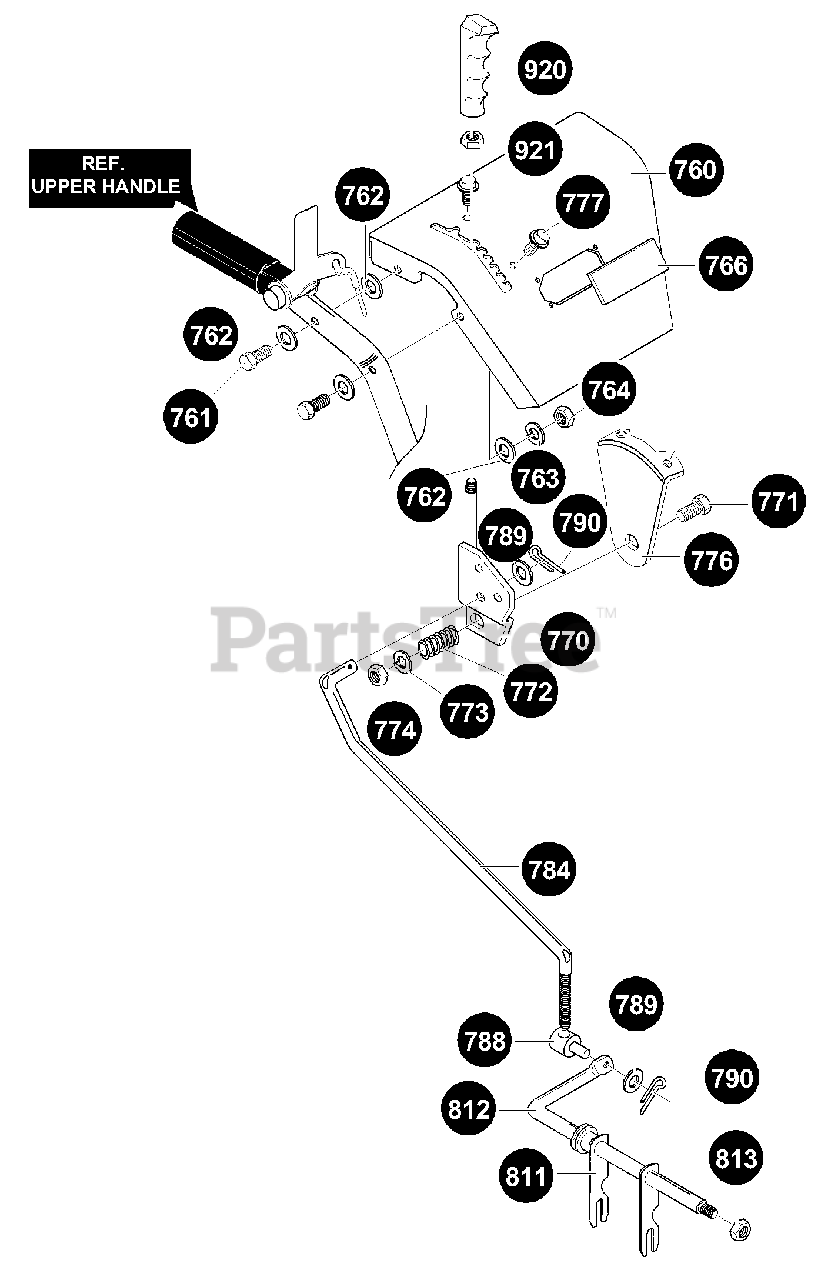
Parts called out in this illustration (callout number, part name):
760	PANEL, CONTROL W/LIGHT
761	SCREW, 5/16-18X1.75
762	FLATWASHER .344X.69X.065
763	WASHER HVSPTLK .328X.60X.09
764	NUT, 5/16-18 REGHEX
766	PLATE, PANEL
770	HANDLE ASSY SPEED CONTROL
771	SCREW 3/8-16X2.00
773	FLATWASHER .406X.81X.065
774	NUT, 3/8-16 HEXNYL
776	BRACKET, SPEED CONTROL
777	SCREW, 5/16-18X.75 WAHHTAP
780	PIN, COTTER .090DIAX.75LG
781	FLATWASHER, .344X.69X.065
784	ROD, SPEED CONTROL
788	NUT, TRUNNION 5/16-24
789	FLATWASHER .344X.69X.065
790	COTTER PIN .090DIAX.73LG
811	BEARING, FLANGED
812	ROD, ASSY YOKE "PANEL"
813	NUT 3/8-16 REGHEXCTRLK
920	HANDLE, 3/8-16 MOLDED
921	NUT, 3/8-16 REGHEXCTRLK
